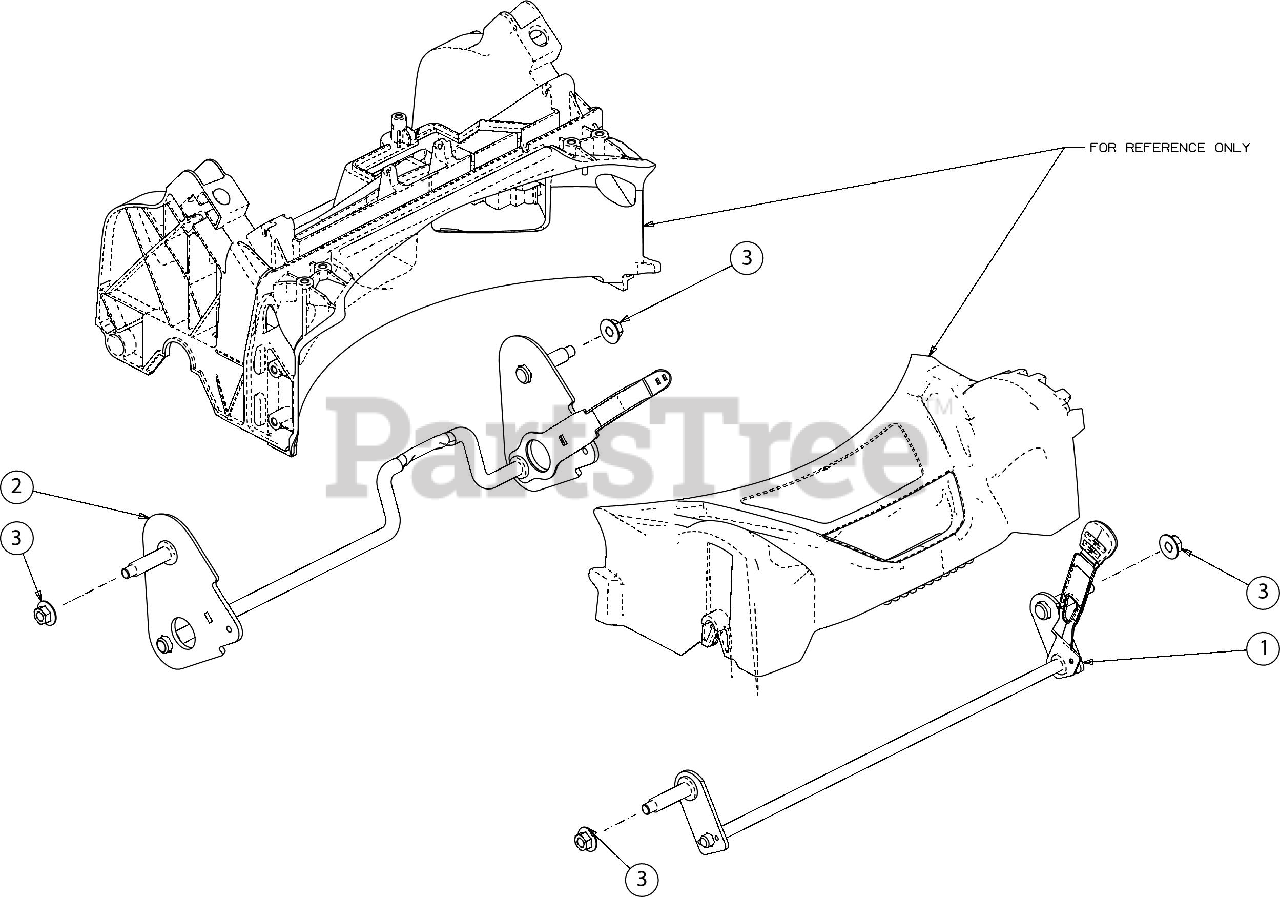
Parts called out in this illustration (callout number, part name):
1	FRONT AXLE ASSEMBLY
2	AXLE ASSEMBLY-HGT AD
3	FLANGE LOCK NUT
